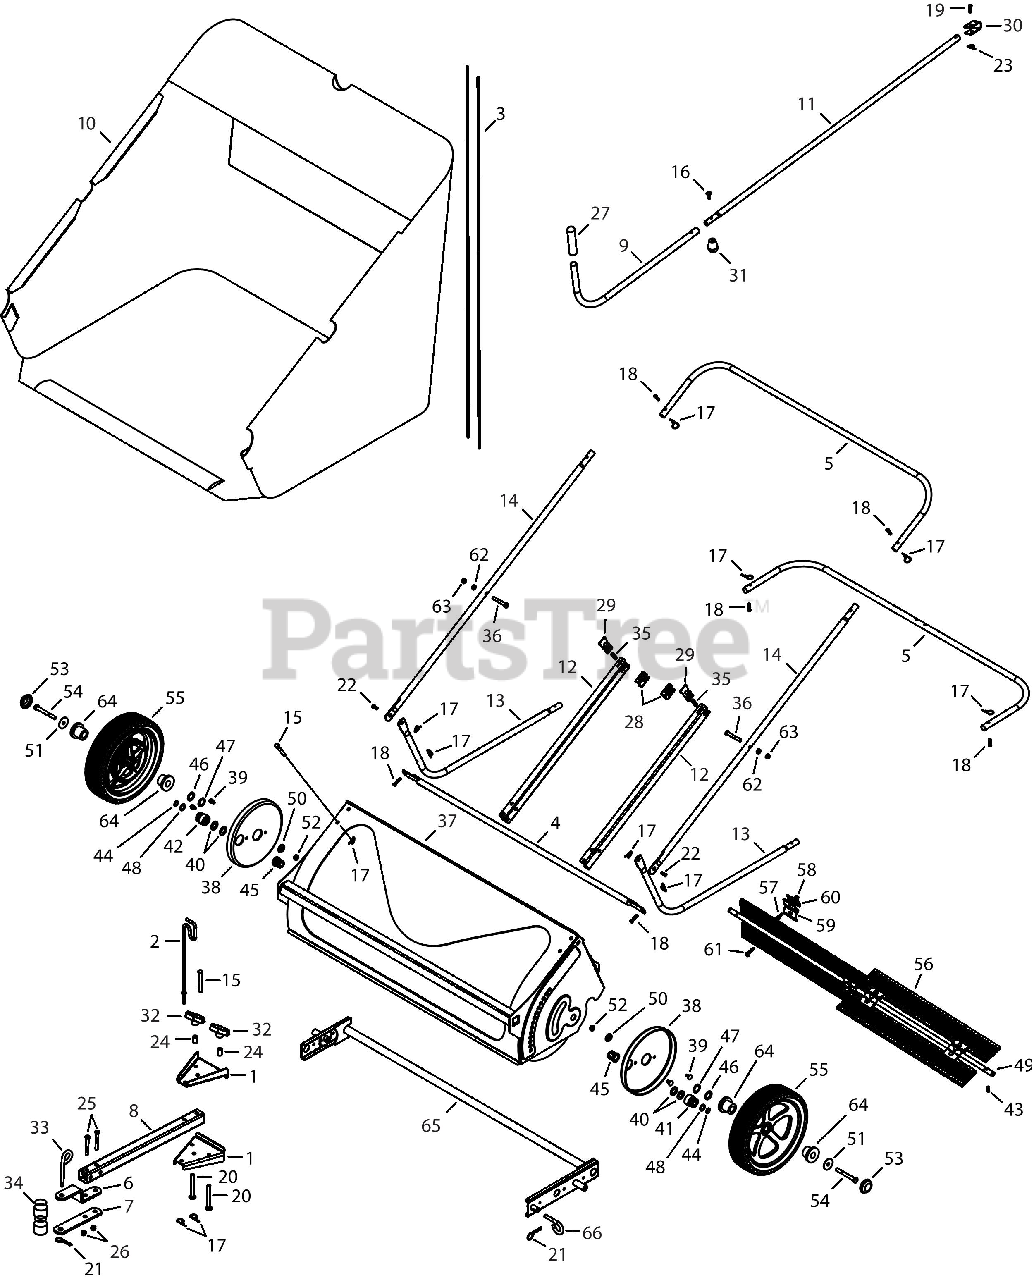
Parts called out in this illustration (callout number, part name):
1	Drawbar Bracket
2	Handle Holder
3	Hopper Support Rod
4	Bag Frame Tube
5	Rear Hopper Tube
6	Hitch Bracket
7	Hitch Bracket (Straight)
9	Lower Handle Tube
10	Hopper Bag
11	Upper Handle Tube
13	Lower Hopper Tube
14	Upper Hopper Tube
15	Clevis Pin, 3/8 x 2-1/4"
16	Bolt, 1/4-20 x 1"
17	Hair Pin, 3/32 x 1.8"
18	Clevis Pin, 1/4 x 1.11"
19	Clevis Pin, 5/16 x 1-1/4"
20	Carriage Bolt, 5/16-18 x 3"
21	Hair Cotter Pin, 3/32 x 2-5/16"
22	Clevis Pin, 3/8 x 1/2"
23	Hair Cotter Pin, .08 x 1-1/8"
24	Spacer, 3/4"
25	Bolt, Hex 5/16-18 x 2-1/2"
26	Nut, Nylock 5/16-18
27	Handle Grip
28	Pivot Rod Support Bracket
29	Pivot Rod Retainer
32	Wing Knob
33	Hitch Pin
35	Compression Spring
36	Hex Bolt, 3/8-16 x 2-1/2"
37	Sweeper Housing
38	Dust Cover
39	Pop Rivet
40	Shim Washer
41	Pinion Gear (LH)
42	Pinion Gear (RH)
43	Dowel Pin, 1/4 x 3/4"
44	Retaining Ring
45	Bearing Assembly
46	Washer, 1-1/8"
47	Washer, 1-1/4"
48	Washer, .598"
49	Brush Shaft
50	Step Spacer
51	Washer, 1-1/4"
52	Nylock Jam Nut, 3/8"
54	Hex Bolt, 3/8-24 x 3-1/4"
57	Hex Bolt, 1/4-20 x 3/4"
58	Nylock Nut, 1/4"
59	Brush Retainer (Double)
60	Brush Retainer (SIngle)
61	Hex Bolt, 1/4-20 x 1"
62	Jam Nut, 3/8"
63	Nylock Jam Nut, 3/8"
64	Wheel Bearing
65	Height Adjustment Tube
66	Pivot Lock Pin 3/8" x 1-1/2"
769-11327	Owner's Manual
